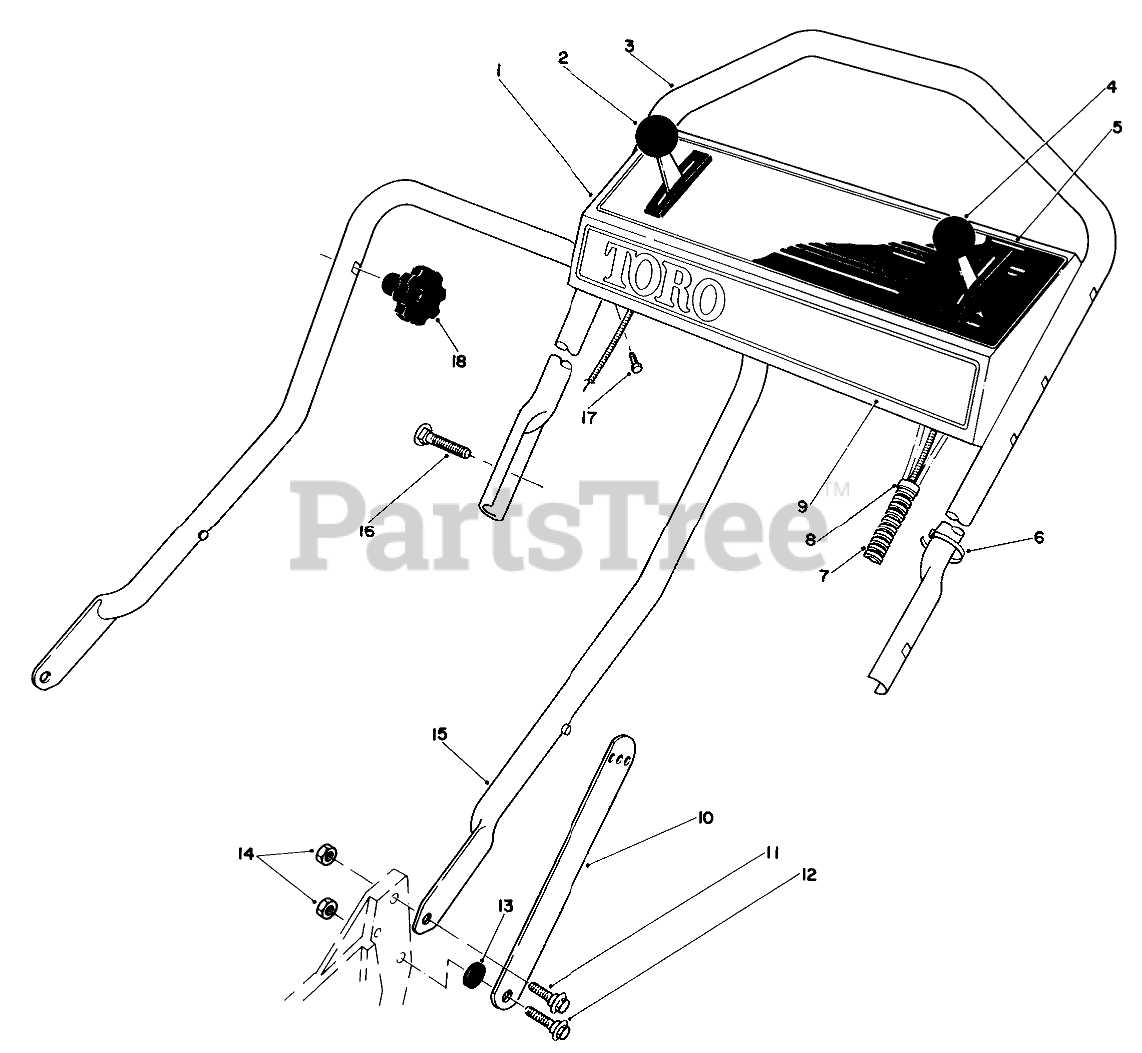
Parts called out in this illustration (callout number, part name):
1	Control Panel (Incl. Ref. #5)
2	GROUND SPEED CONTROL
3	Handle-Upper
4	SERVICE THROTTLE CONTRO
5	Decal-Instruction
6	TIE-CABLE
7	CONTROL CABLE COVER
8	FITTING-RING
9	Decal-Toro
10	Handle Latch
11	SCREW-SHOULDER
12	SCREW-SHOULDER
13	SPACER
14	Locknut
15	Handle-Lower
16	5/16-18 X 2 HNDLE SCREW
17	SCREW-HWHTF
